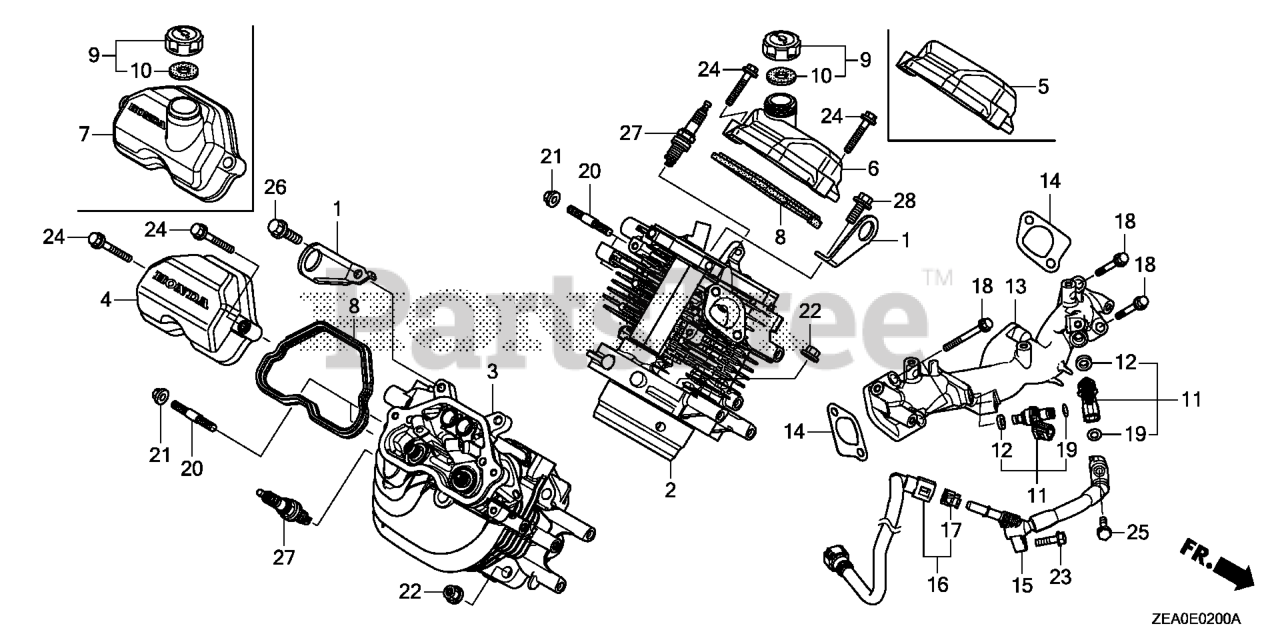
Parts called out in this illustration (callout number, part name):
1	HANGER, ENGINE
2	CYLINDER HEAD (#1)
3	CYLINDER HEAD (#2)
4	COVER, CYLINDER HEAD
6	COVER, CYLINDER HEAD
8	GASKET, HEAD COVER
9	CAP ASSY., OIL FILLER
10	GASKET, OIL FILLER CAP
11	INJECTOR ASSY., FUEL
12	RING, SEAL
13	MANIFOLD, IN.
14	GASKET, IN. MANIFOLD
15	HOSE A, FUEL
16	HOSE B, FUEL
18	BOLT, FLANGE (8X55)
19	O-RING (6.3X2.2)
20	BOLT, STUD (8X22)
21	NUT, FLANGE (8MM)
22	NUT, FLANGE (10MM)
23	BOLT, FLANGE (6X22)
24	BOLT, FLANGE (6X30)
25	BOLT, FLANGE (6X35)
26	BOLT, FLANGE (8X16) Use from Engine SN 1000016.
27	SPARK PLUG (BPR5ES) (NGK)
28	BOLT, FLANGE (8X16) Use from Engine SN 1000016.
